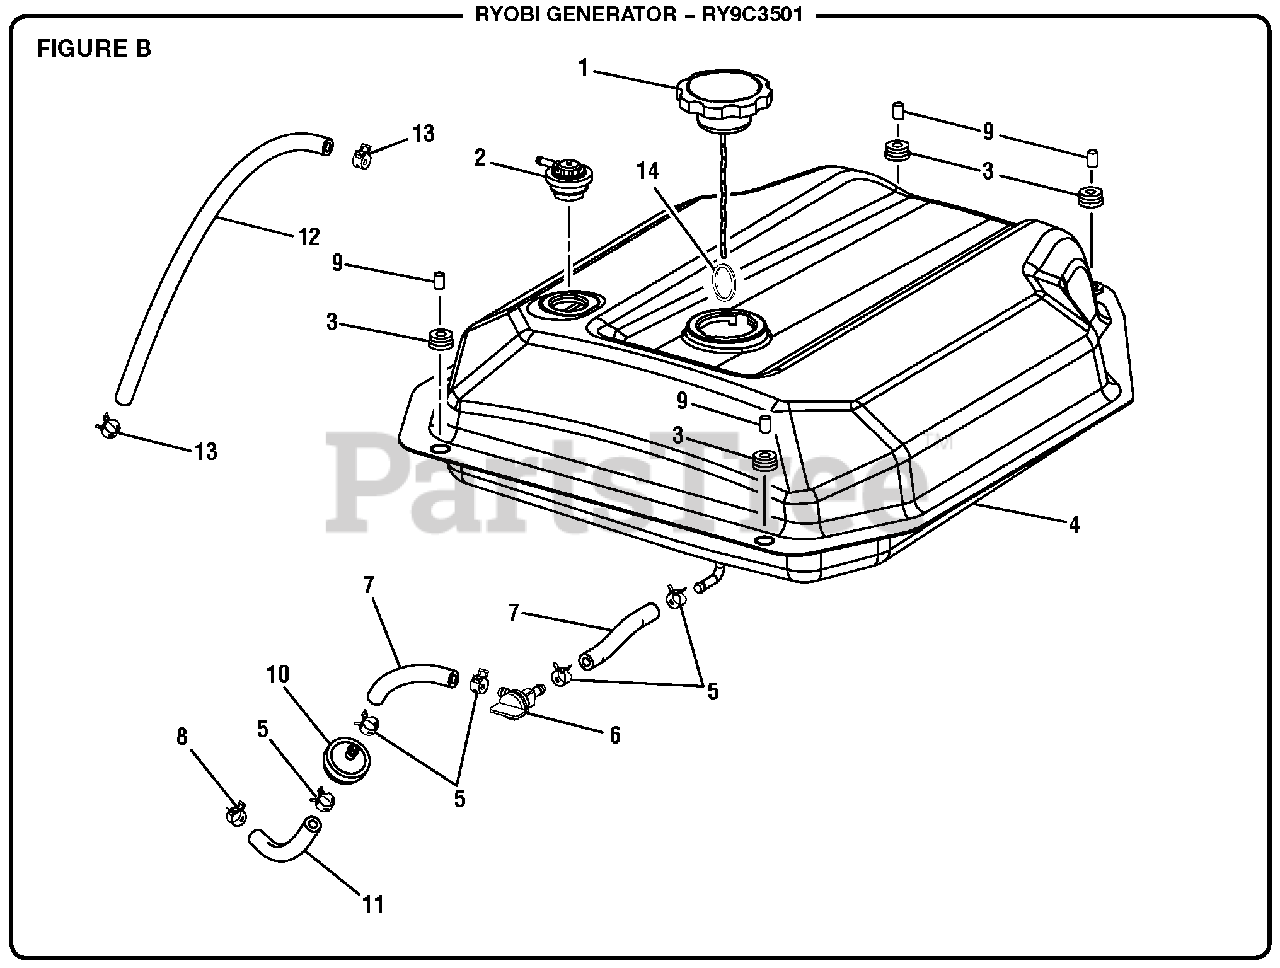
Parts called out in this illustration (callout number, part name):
1	Fuel Tank Cap
2	Fuel Tank Vapor Vent
4	Fuel Tank
5	Hose Clamp
6	Fuel Shut Off Valve
7	Fuel Line (90 mm)
8	Hose Clamp (5/16 in.)
10	Fuel Line Filter
11	Fuel Hose (150 mm)
12	Vent Hose
13	Fuel Line Clamp (7/16 in.)
14	Ring Clip
